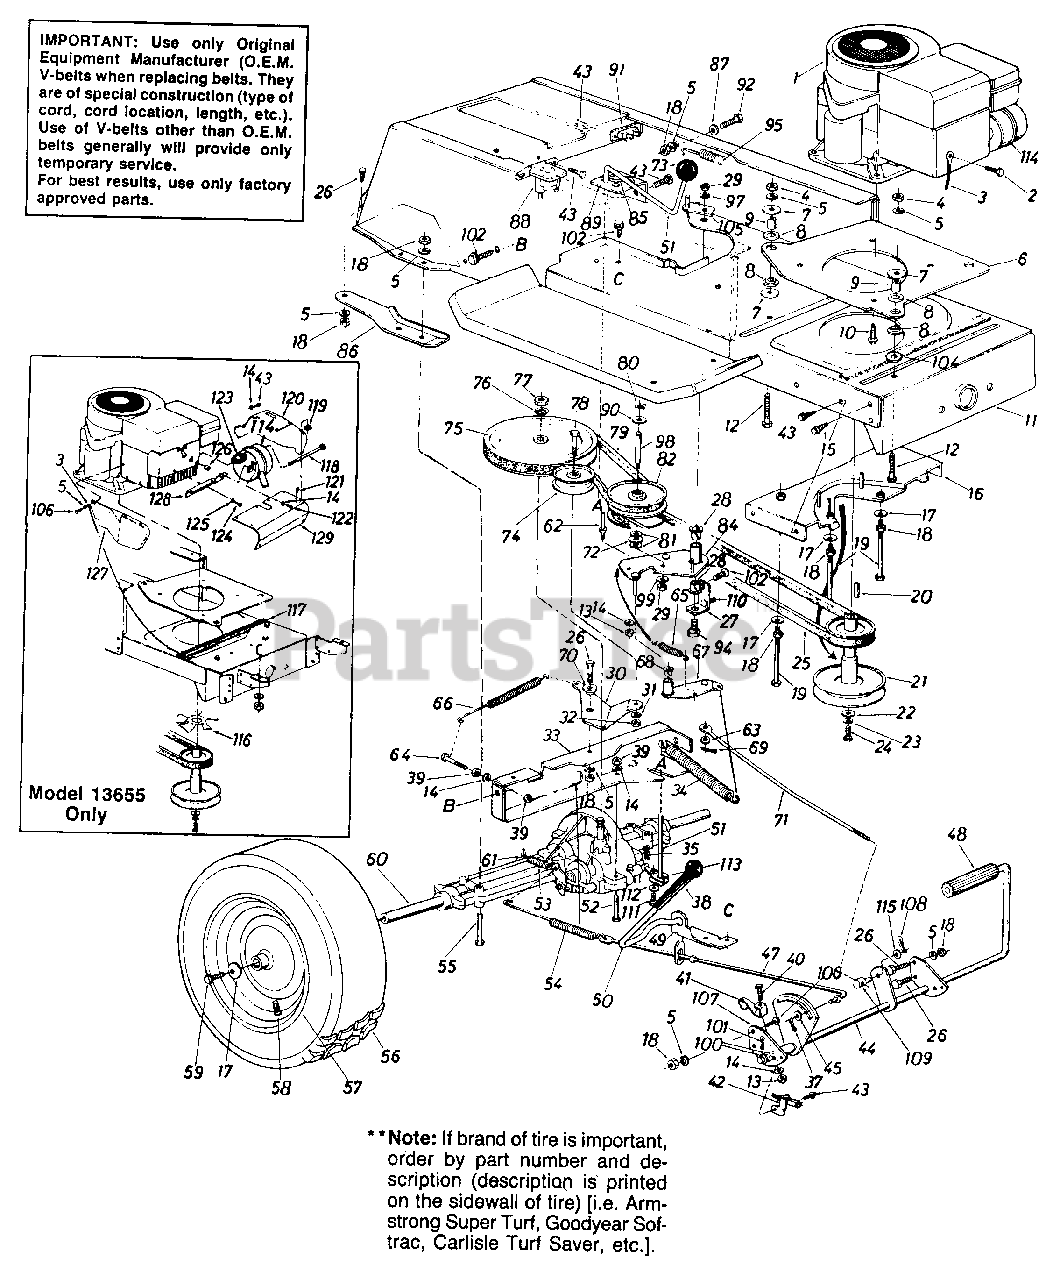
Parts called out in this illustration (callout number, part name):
1	Engine
2	Hex Bolt 1/4-20 x .62" Lg.
3	Electric Ground Wire
4	Hex Nut 5/16-24 Thd.
5	L-Wash. 5/16" I.D.
8	Engine Mounting Grommet
9	Spacer
10	Hex Bolt 3/8-16 x 1.25" Lg.
11	Lower Frame Ass'y.
12	Hex Bolt 5/16-24 x 1.25"
13	Hex Nut 1/4-20 Thd.
14	L-Wash. 1/4" I.D.
15	Hex Wash. Hd. AB-Tap Scr. 5/16" x.75" Lg.
16	Belt Guard Brkt. Ass'y.
17	Bell-Wash. .345" I.D. x .88"
18	Hex Nut 5/16-18 Thd.
19	Hex Bolt 5/16-18 x 4"
20	Sq. Key 1/4" X 1/4" X 2.00"
21	Engine Pulley
22	Fl-Wash. 7116" I.D. x 1.25"
23	L-Wash. 7116" I.D.
24	Hex Bolt 7/16-20 x 1.50" Lg.
25	Variable-Speed Belt
26	Hex Bolt 5/16-18 x .75" Ls.
27	Bearing Shaft Bracket Ass'y.
28	Flanged Nyliner Brg. 518" I.D. x .88" Lg.
29	LHex Nut 3/8-24 Thd.
30	Idler Bracket
31	L-Wash. 3/8" I.D.
32	Hex Nut 3/8-24 Thd.
35	Inter. Cott-Pin
37	Cotter Pin 3132" Dia. x .75"
38	Grip Black
39	Hex Nut 1/4-28 Thd.
40	Hex Bolt 1/4-20 X 1.00" Lg.
41	Switch Actuator
42	Safety Switch
43	Hex Wash. Hd. S-Tap Scr. 1/4-20 x .50" Lg.
44	Clutch/Brake Pedal Ass'y.
45	Fl-Wash.
47	Brake Rod 20.9" Lg.
48	Foot Pad
49	Brake Lever Bracket
50	Hill Holder Brake Handle
51	Shift Lever Ass'y.
52	Hex Bolt 1/4-28 x 1.75" Lg.
53	Ext. Spring .38" O.D. x 2.5"
54	Ext. Spring .59" O.D. x 7.08"
55	Hex Bolt 5/16-18 x 2.75"
58	Air Valve
59	Hex Bolt 5/16-24 x .75" Lg.
60	Transaxle Complete
61	Brake Return Spring Anchor
62	Belt Guard Pin 1/4-20 Thd.
63	Fl-Wash. .34" I.D. x .68" O.D.
64	Hex Bolt 1/4-28 x 1.25" Lg.
65	Ext. Spring
66	Ext. Spring .62" O.D. x 6.12"
68	Flanged Bearing
69	Cotter Pin 3132" Dia.
70	Shoulder Spacer .27" Lg.
71	Speed Control Link
72	Truss Bearing .56 Dia. x 1.25"
73	Ball Knob
74	Fl-Idler Pulley 3.25" x .75"
75	1/2" "V"-Pulley 8.0" O.D. x.501" I.D.
76	L-Wash. 1/2" I.D.
77	Hex Jam Nut 1/2-20 Thd.
78	Hex Bolt 3/8-24 x 1.75" Lg.
79	Variable Speed Belt
80	Snap Ring .56" Dia.
81	Fl-Wash.
82	Variable Speed Pulley Ass'y. 5" O.D.
86	Axle Support Brkt. R.H.
87	Fl-Wash. .34 I.D. x 1.12 O.D.
88	Solenoid
89	Shift Lever Bracket
90	Teflon Washer .565" I.D.
91	Circuit Breaker
92	Hex Bolt 5/16-18 x 1.50" Lg.
94	Shld. Bolt 3/8-24 x 3.12" Lg.
95	Ext. Spring .99" O.D. x 11"
97	Bell-Wash. .38" I.D. x .88"
98	Shaft .56" Dia. x 3.875" Lg.
99	Bell-Wash. .39" I.D. x 1.12"
100	Fl-Wash.
101	Cotter Pin 3132" Dia. x 1.0"
102	Hex Wash. Hd. Scr. 5/16-18 x.62" Lg.
104	Fl-Wash. .32" I.D. x 1.25"
105	Belt Guard
106	Truss Mach. Scr. 5/16-18 x .75" Lg.
107	Pedal Bracket
108	Cotter Pin 3/32" Dia. x .75"
109	Ferrule
110	Hex Bolt 5/16-18 x 1.0" Lg. (Gr. 5)
111	Hex Bolt 1/4-28 x .50" Lg.
112	Bell-Wash. .265" I.D. x .75"
113	Shift Lever Link Ass'y.
114	Muffler
115	Fl-Wash. .385" I.D. x .62" O.D.
117	Mylar Foam
118	Shld. Bolt 5/16-18 Thd.
119	Speed Nut #10-24 Thd.
120	Muffler Heat Shield L.H.
121	Hex AB-Tap Scr. #10 x .5" Lg.
122	Hex Bolt 1/4-20 x .75" Lg.
123	Gasket
124	Hex Bolt 1/4-20 x 3/8" Lg.
125	Spr. Wash. .265" I.D. x .562"
126	Spacer.28" I.D. x .5" O.D.
127	Muffler Heat Shield R.H.
128	Muffler Bracket
129	Muffler Heat Shield Front
